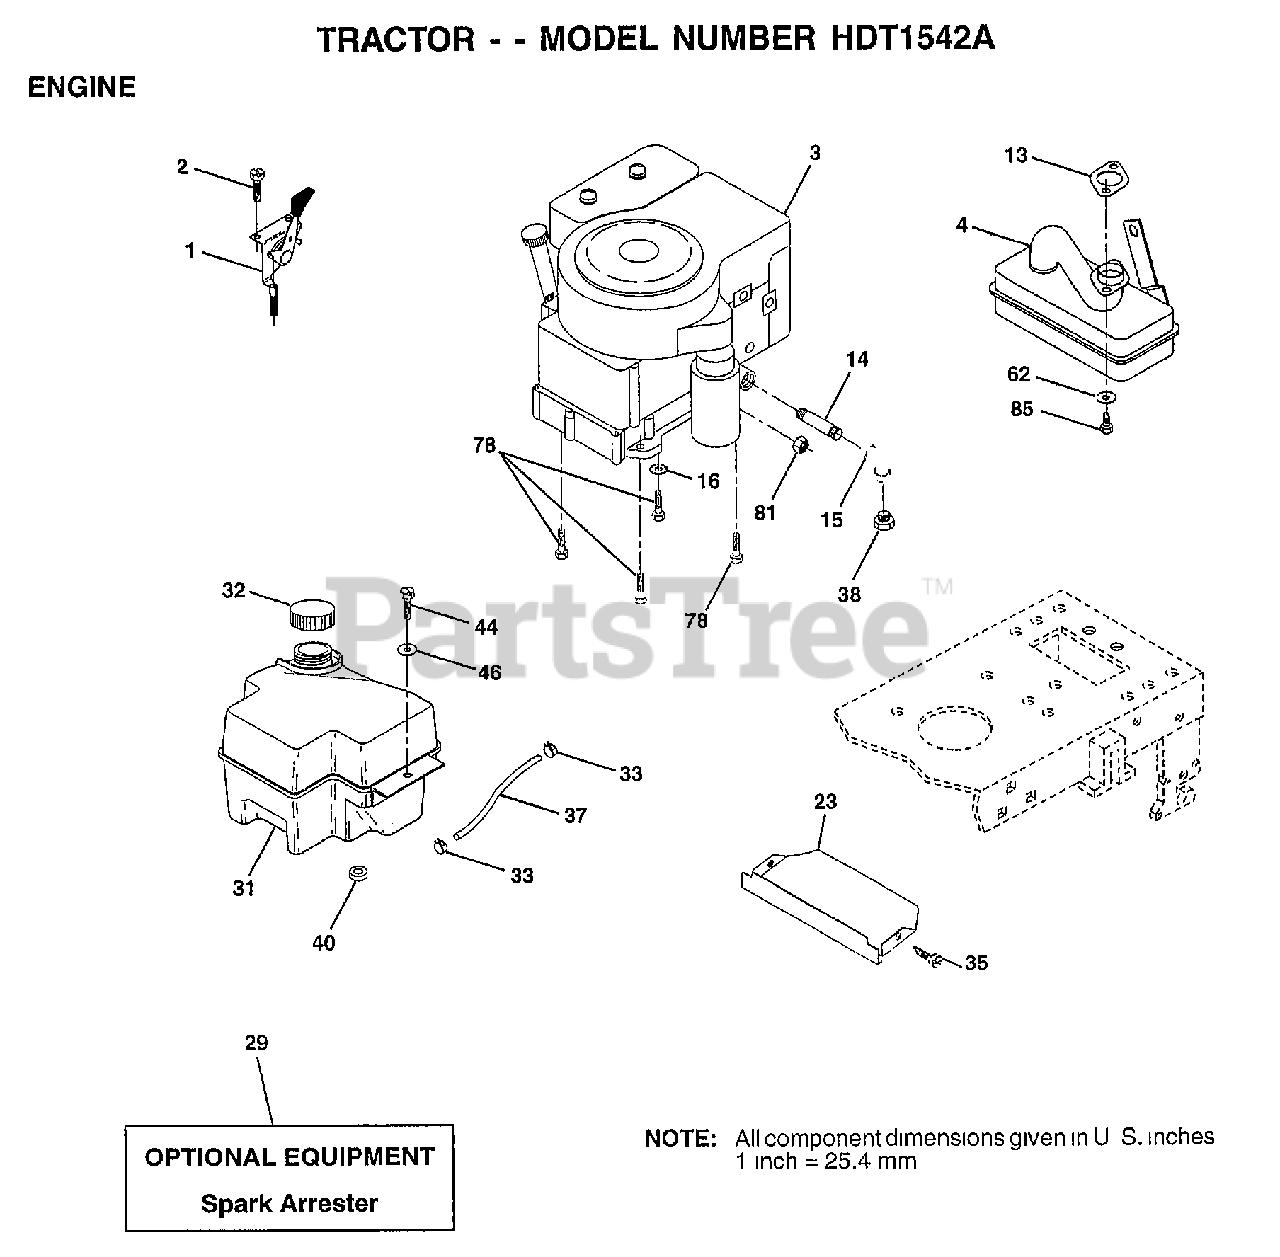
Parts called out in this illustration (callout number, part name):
1	CONTROL THROTTLE
2	SCREW LT
4	MUFFLER
13	GASKET MUFFLE TEC
14	PIPE NIPPLE LT
15	ELBOW
16	LOCKWASHER
23	SHIELD.BRN/DBR.GD
31	TANK.FUEL.FRONT.
32	CAP ASM FUEL
33	HOSE CLAMP
35	SCREW
37	LINE FUEL
44	SCREW HEX CRT
46	WASHER
62	LOCKWASHER
78	SCREW
81	NUT
85	SCREW HEX HD CAP
